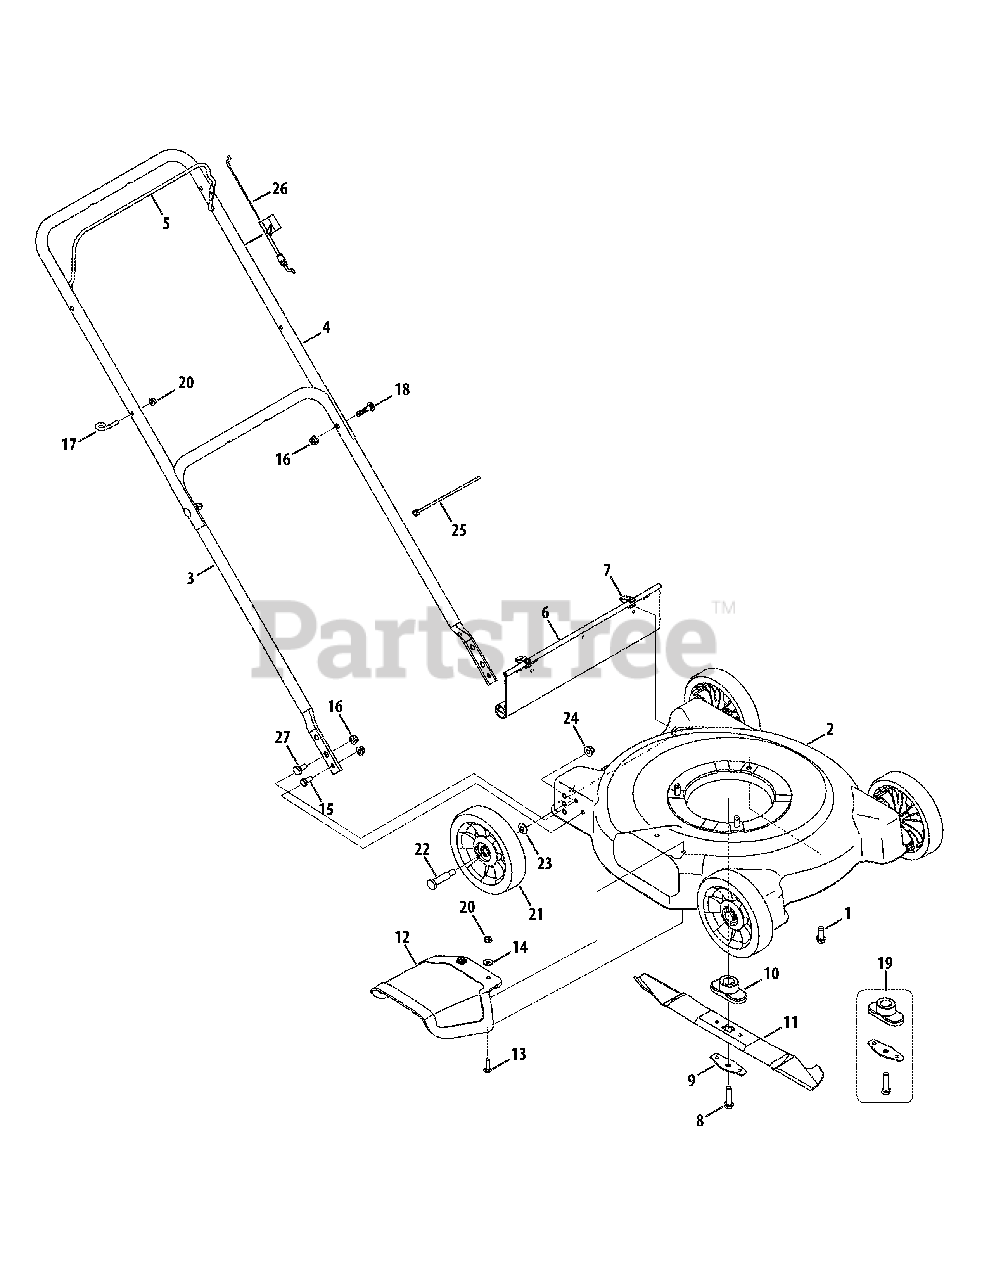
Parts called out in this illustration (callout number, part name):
1	Hex Ind. Washer Screw, 3/8-16 x 1.0
2	Cutting Deck: 20"
4	Upper Handle
5	Control Handle (Bail)
6	Rear Flap
7	Hinge Clip
8	Screw, 3/8-24 x 1.5"
9	Blade Bell Support
10	Blade Adapter
11	Cutting Blade
12	Discharge Chute
13	Carriage Screw, 1/4-20 x 1.0"
14	Flat Washer
15	Hex Screw, 5/16-18 x .75"
16	Flange Lock Nut, 5/16-18
17	Eye Bolt
18	Carriage Bolt, 5/16-18 x 1.5"
19	Blade Adapter Kit
20	Flange Lock Nut, 1/4-20
21	Wheel, 7" Star-Dia., Oys. Gray
22	Shoulder Screw, .498 x 1.635
23	Bell Washer
24	Flange Lock Nut, 3/8-16
25	Cable Tie
26	Control Cable
27	Shoulder Screw, 5/16-18 x.428"
